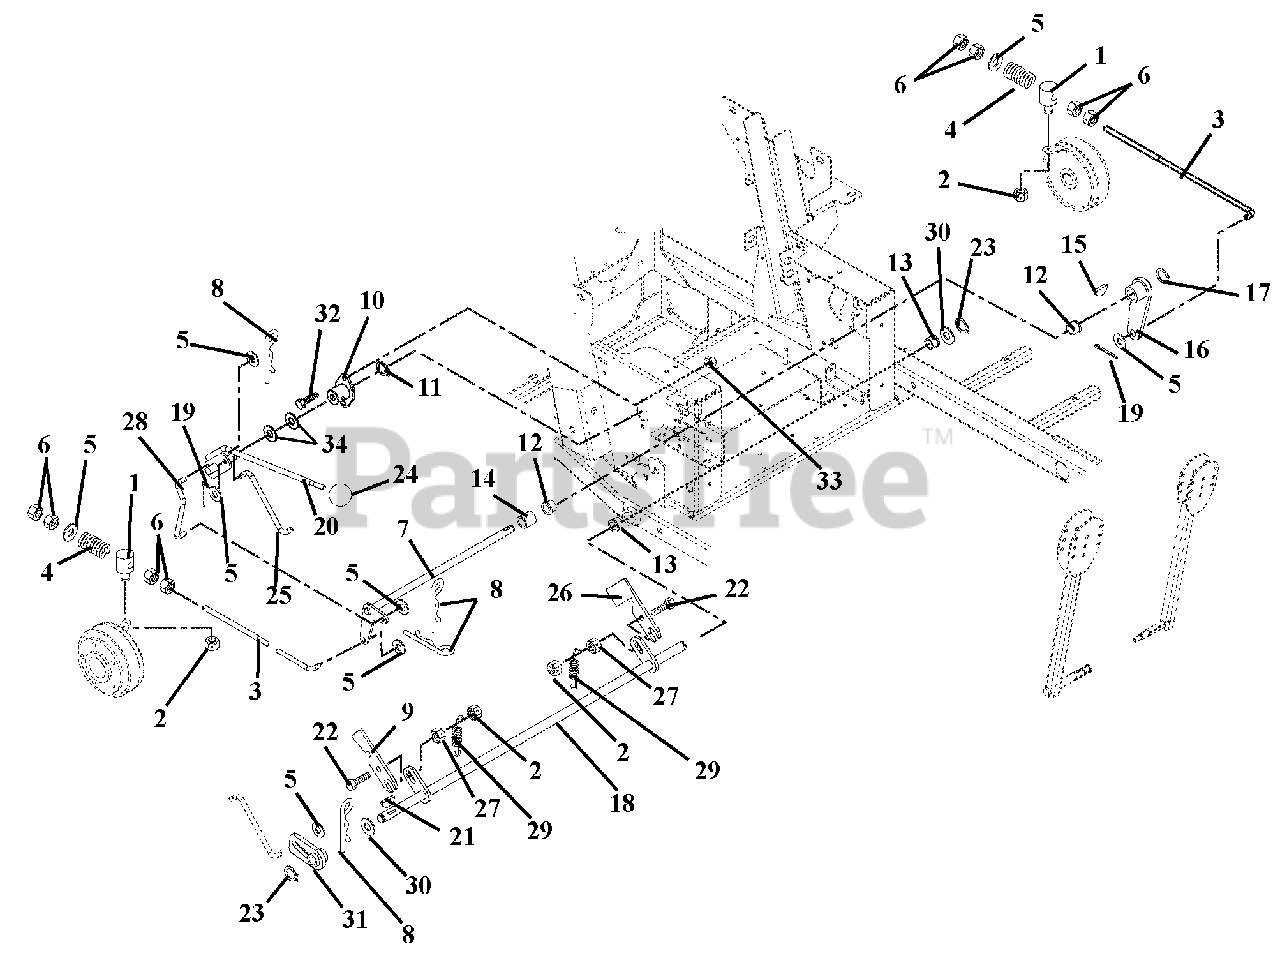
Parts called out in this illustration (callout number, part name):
1	Pivot, Brake Rod
2	Nut, Locking Center .31-18
3	PTO Link Rod
4	Spring, Compression .142 x .710 x 1.75
5	Washer, Flat Steel .406 x .812 x .065
6	Nut, Hex .38-16
7	Shaft, Brake Cross
8	Pin, Hair
9	Slide, Interlocking Brake
10	Bushing, Flange
11	Ring, Retaining External .625 x .05
12	Bushing, Flange Nylon .762 x 1.00 x .58 x 1.48
13	Bushing, Flange .515 x .75 x .745 x 1.00
14	Bushing, Sleeve .75 x 1.00 x .75
15	Key, Woodruff .19 x .75 Hard #9
16	Arm, Brake
17	Ring, Retaining External .69 x .077
18	Weldment, Mechanical Brake
19	Pin, Cotter External .09 x .75
20	Weldment, Brake Actuating
21	Key, Woodruff .13 x .63
22	Bolt, Round Head Square Neck .31-18 x 1.25 Grade 5
23	Ring, Retaining External .50 x .05
24	Knob, Steering Lock
25	Linkage, Brake Actuating
26	Interlock, Safety Switch
27	Nut, Locking Top Flange .31-18
28	Linkage, Brake Actuating
29	Spring, Tension .048 x .44 x 1.75
30	Washer, Flat Steel .505 x 1.00 x .062
31	Weldment, Parking Brake Hub
32	Bolt, Hex .31-18 x .75 Grade 5
33	Nut, Locking Top Flange .31-18
34	Washer, Flat Steel .630 x 1.25 x .062
